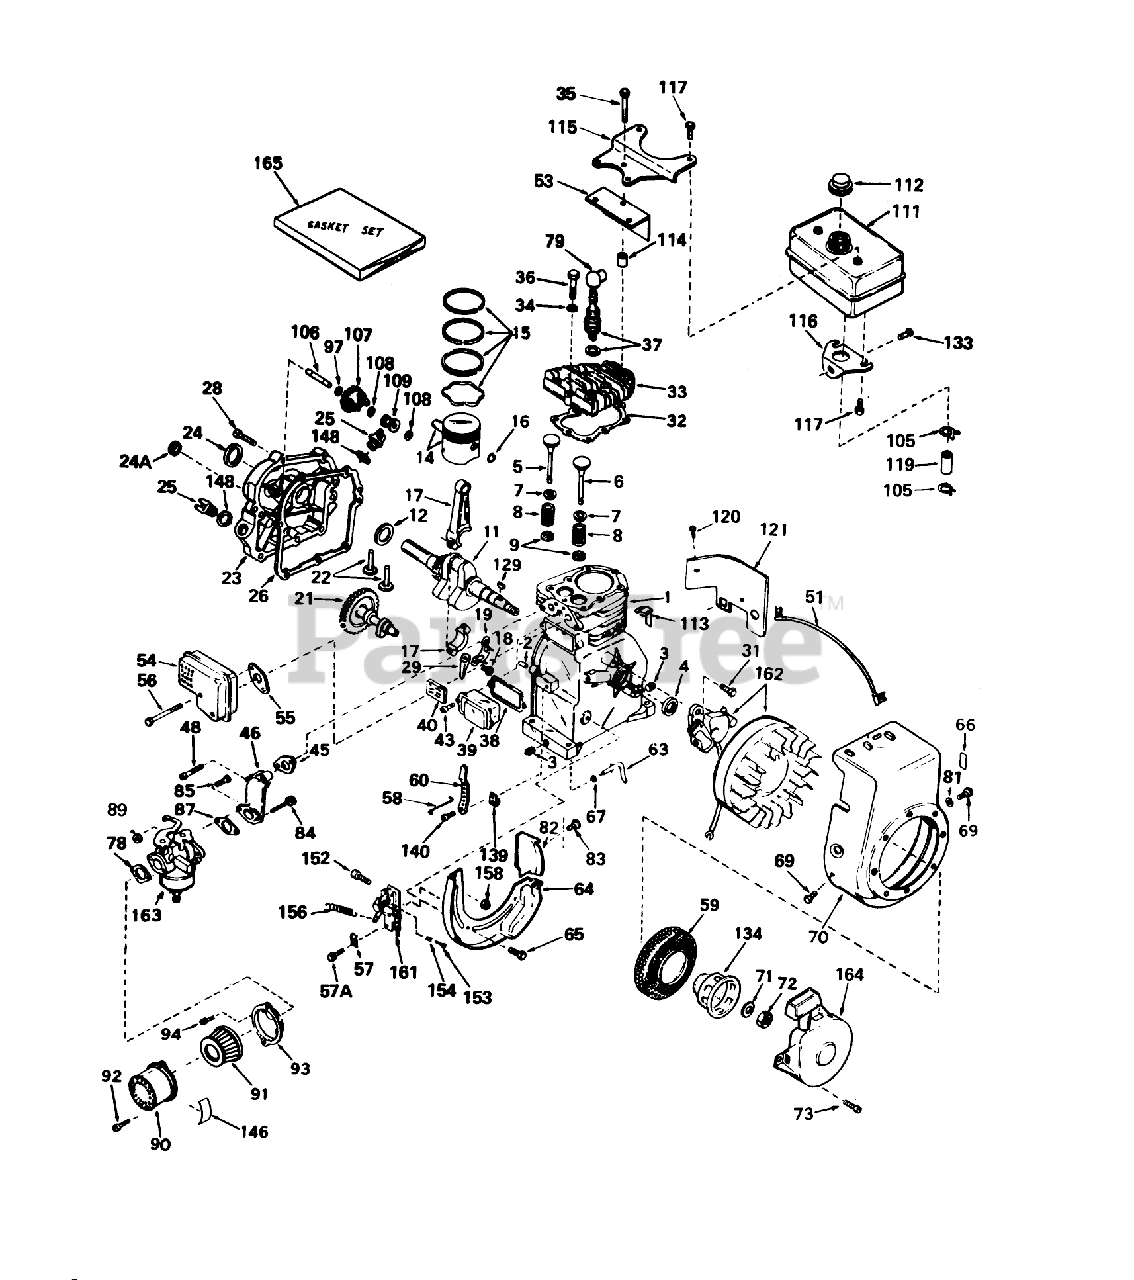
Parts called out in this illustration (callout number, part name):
1	Cylinder Assy. (Incl. #2, 3 4)
2	Pin-Dowel
3	Plug-Drain, Oil (SQH 1/4-18)
4	Seal-Oil
5	Valve, Intake (Standard) (Incl. Nos. 7, 9 10)
5	Valve, Intake (1/32" Oversize) (Incl. Nos. 7, 9 10)
6	Valve, Exhaust (Standard) (Incl. Nos. 8, 9 10)
6	Valve, Exhaust (1/32" Oversize) (Incl. Nos. 8, 9 10)
7	Cap-Upper Valve Spring
8	Spring-Valve
9	Cap-Valve, Spring
11	Crankshaft Assy.
12	Washer-Thrust
14	Piston Pin Assembly (Incl. 2 of No. 14) (.010 Oversize)
14	Piston Pin Assembly (Incl. 2 of No. 14) (.020 Oversize)
15	Ring Set Piston (Std.)
15	Ring Set Piston (.010 Oversize)
15	Ring Set Piston (.020 Oversize)
16	Ring-Retaining, Piston Pin
17	Rod Assembly, Connecting (Incl. Nos. 17 18)
18	Connecting Rod Bolt
19	Plate Lock
21	Camshaft (Compression Release) (Extended)
22	Lifter-Valve
23	Cover, Cylinder (Incl. Nos. 24, 24A, 25, 106 148)
24	Seal-Oil
24A	Seal, Oil
25	Plug-Fill, Oil
26	Gasket-Cylinder Cover
28	Screw
29	Dipper-Oil
31	Screw
32	63573 GIL 42 SNWTHW
33	Head Cylinder
34	Washer
35	Screw Hex Hd. Cap
36	Screw
37	Plug, Spark (J17LM or equiv.)
38	Gasket Breather
39	Breather Assembly (Incl. Nos. 52 84)
40	Element-Breather
43	Screw
45	Gasket, Intake
46	Pipe, Intake
48	Screw
51	Wire, Ground
53	Baffle-Heat
54	Muffler
55	Gasket-Intake
56	Screw, Hex hd. cap
57	Conduit
57A	Screw (10-32 x 3/8)
58	Link-Governor to Throttle
59	Screen-Starter
60	Lever-Governor
63	Rod-Governor
64	Baffle-Blower Housing
65	Screw (1/4-20x19/32)
66	Decal, Name Instruction
67	Washer-Flat
69	Screw
70	Housing Blower
71	Washer-Spring
72	Hex Nut
73	Screw
78	Gasket
79	Cover-Spark Plug
81	Washer
82	Baffle-Extension
83	Screw-Hex Washer Hd.
85	Screw-Fil. Hd.
87	Gasket
89	Nut and Lock Washer (1/4-28)
90	Body
91	Element
92	Screw
93	Bracket, Air cleaner
94	Screw (10-32 x 1/2)
97	Washer-Flat
105	Clamp-Line, Fuel
106	Shaft-Governor
107	Governor Gear ASM
108	Ring-Retaining
109	Spool-Governor
111	53023/VAR.10/16HP O
112	Cap, Fuel
113	Clip-Wire
114	pacer
115	Bracket, Fuel tank
116	Bracket, Fuel Tank Lower
117	Screw (1/4-15x7/8)
119	Line-Fuel
120	Screw
121	Extension-Blower
129	Key Flywheel
133	Screw (1/4-20x19/32)
134	Cup, Starter
139	Clamp-Lever, Governor
140	Screw
146	Decal
148	Gasket
152	Screw, Hex Slotted Hd.
153	Screw
154	Spring-Compression
156	Spring-Extension
158	Nut-Lock
161	Bracket Assy., Control (Incl. Nos. 149, 150, 151 152)
162	Magneto
163	Carburetor (Incl. No.87)
164	Starter, Rewind
165	Gasket
